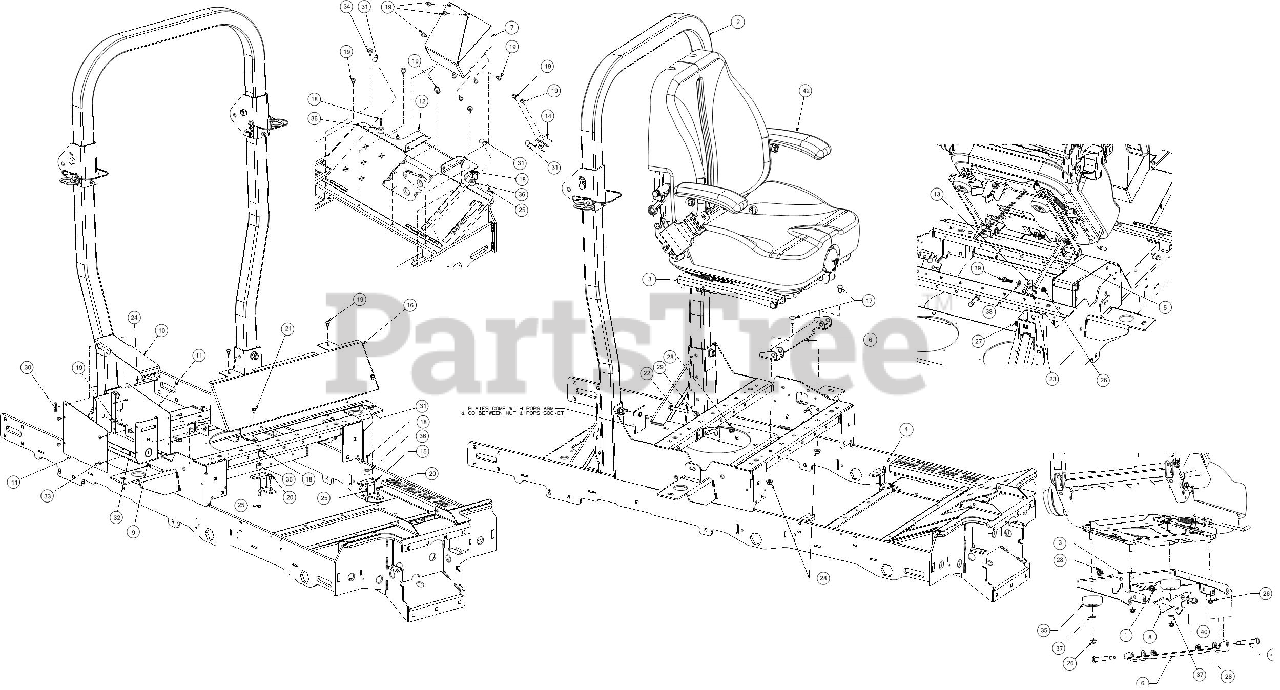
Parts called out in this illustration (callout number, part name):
1	HANDLE SPRING (LH)
2	ROPS ASSEMBLY
3	SEAT MOUNT BRACKET
4	FLOOR TRAY PANEL
5	SEAT LOCKOUT BRACKET
8	SEAT LATCH LEVER
9	STORAGE TOOLBOX
10	STORAGE TOOLBOX LID
11	SIDE PANEL BOX
12	STEERING PANEL COVER
13	SEAT LOCKOUT MOUNT
14	STOP BRACKET
15	FLOOR MOUNT BRACKET
17	CARRIAGE BOLT 3/8-16 X .750 GR5
18	SCREW 10-24 X .750
19	SCREW 1/4-20 X .5
20	SCREW 1/4-20 X.500
21	SCREW 1/4-20 X .375
22	HEX SCREW-3/8-16X2.5 GR5
23	SCREW 1/4-20X.75 GR5
26	FLANGE LOCK NUT 5/16-18
27	FLANGE LOCK NUT
29	HEX NUT
30	BOW TIE COTTER PIN 1/4-5/16
31	RATCHET CLIP
32	ADHESIVE PAD
33	FULL TUBULAR RIVET
34	BUMPER, .62 DIA X .3
35	RUBBER BUMPER
36	RUBBER BUMPER
37	FLAT WASHER
38	FLAT WASHER .469X.750X.054
39	SHOULDER SCREW .437
40	SHOULDER SCREW .50X.925
41	SHOULDER SCREW .50 X 2.23 3/8-16
42	SEAT (COMMERCIAL)
